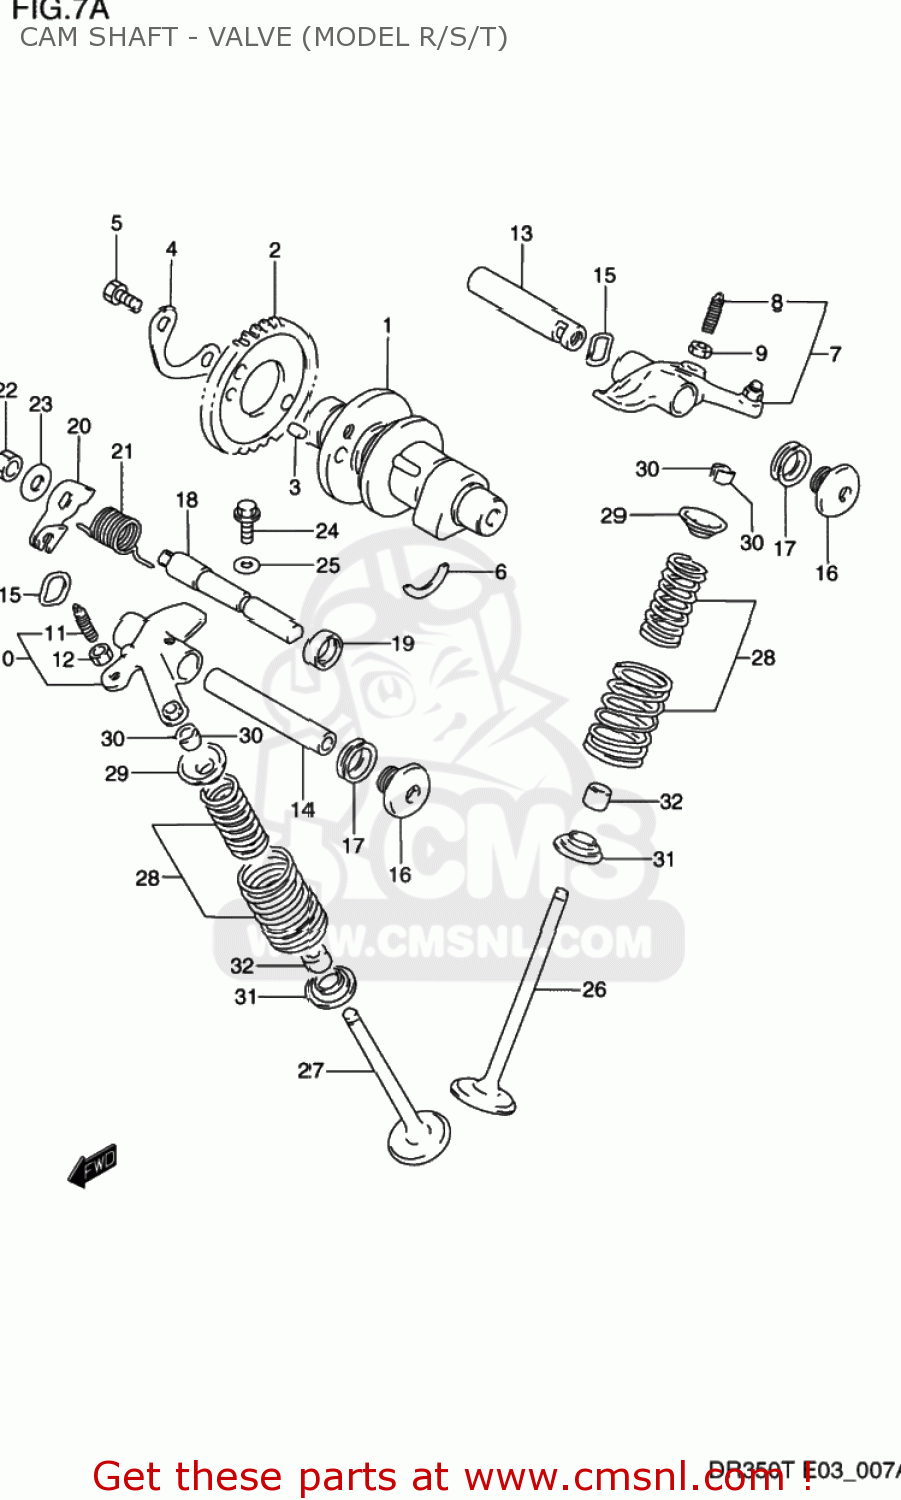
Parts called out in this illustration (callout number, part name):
1	SHAFT COMP,CAM
2	SPROCKET,CAMSHAFT
3	PIN(5X8)
4	WASHER,SPROCKET
5	BOLT(6X10.5)
6	C RING
7	ARM,VALVE ROCKER,INTAKE
8	SCREW,TAPPET ADJUSTING
9	NUT,TAPPET ADJUSTING
10	ARM,VALVE ROCKER EXHAUST
11	SCREW,TAPPET ADJUSTING
12	NUT,TAPPET ADJUSTING
13	SHAFT,VALVE ROCKER ARM INTAKE
14	SHAFT,VALVE ROCKER ARM EXHAUST
15	WASHER
16	PLUG,14X12
17	GASKET(13.8X18.8X4.8) (NAS)
18	SHAFT,DECOMP
19	SEAL,OIL(10X17X6)
20	LEVER,DECOMPRESSION SHAFT
21	SPRING
22	NUT
23	WASHER
24	BOLT
25	GASKET(6.4X11.5X0.8) (NAS)
26	VALVE,INTAKE
27	VALVE,EXHAUST
28	SPRING SET,VALVE
29	RETAINER,VALVE SPRING
30	COTTER VALVE
31	SEAT,VALVE SPRING
32	SEAL,OIL(5X10X9.7)
